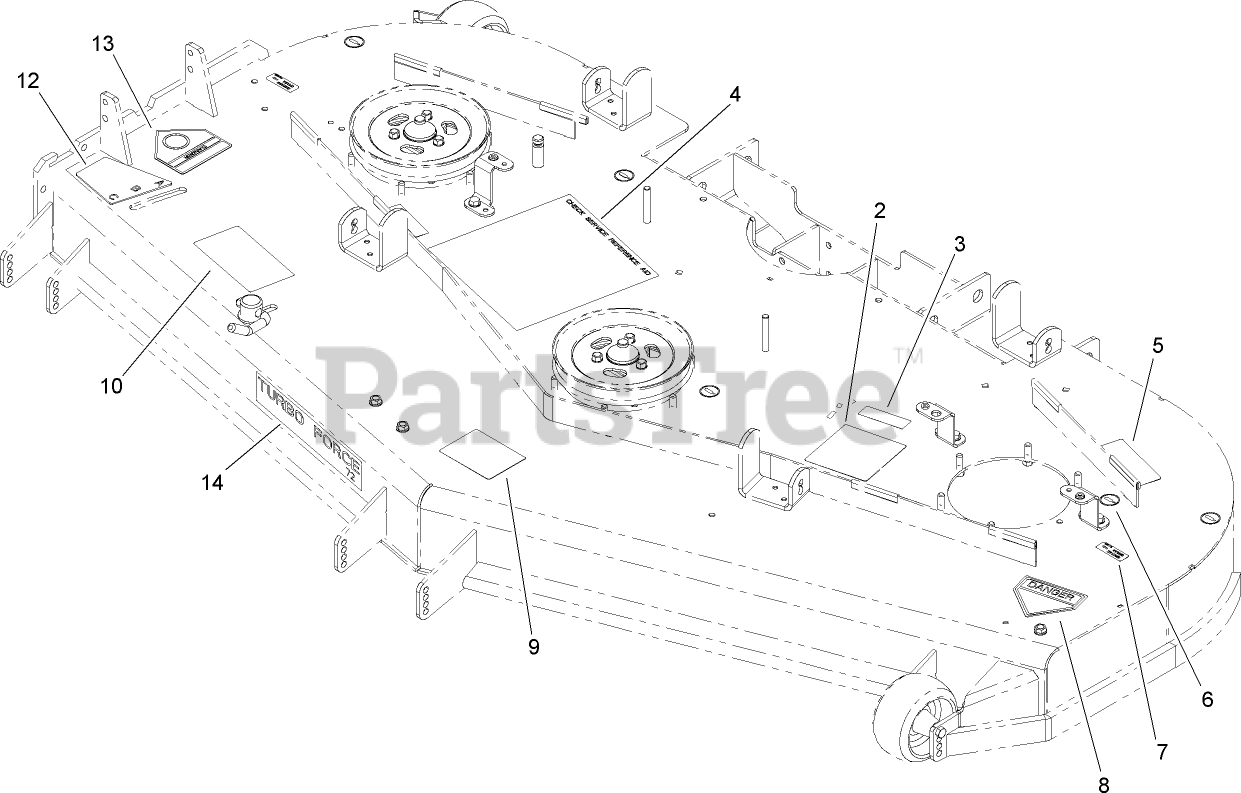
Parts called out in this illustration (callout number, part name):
2	DECAL-ROUTING, BELT
3	DECAL-COVER, MISSING
4	DECAL-CHECK, SERVICE
5	DECAL-TORQUE
6	DECAL-GREASE
7	Decal-Grease
8	DECAL-DANGER
9	DECAL-SCALP, ANTI
10	DECAL-DANGER, THROWN OBJECT
12	DECAL-ADJUSTMENT, BAFFLE
13	DECAL-DANGER
